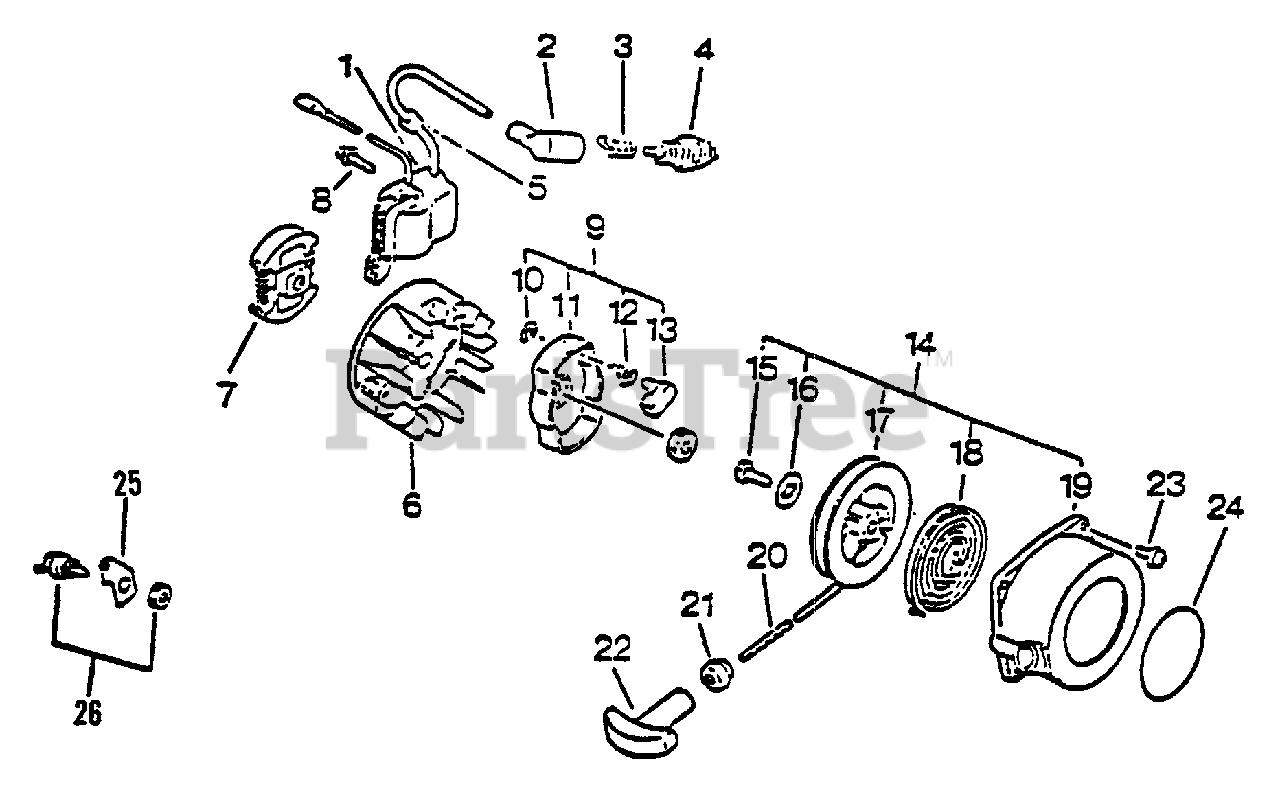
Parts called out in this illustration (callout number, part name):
1	COIL, IGNITION
2	CAP, SPARK PLUG
3	TERMINAL, SPARK PLUG CAP
4	SPARK PLUG -- BPM-7A
4	SPARK PLUG -- BPMR-7A
5	GROMMET
6	FLYWHEEL
7	CLUTCH ASSY
8	SCREW - 4X22
9	STARTER PAWL ASSY
10	RING, RETAINING - 4
11	CATCHER, PAWL
12	SPRING, RETURN
13	PAWL, STARTER
14	STARTER ASSY
16	WASHER
17	REEL, ROPE
18	SPRING, REWIND
19	CASE, STARTER
20	ROPE, STARTER - 3X890
21	GUIDE, ROPE
22	GRIP, STARTER
23	SCREW - 4X16
24	LABEL - ECHO
25	IGNITION SWITCH ASSY
26	BRACKET, SWITCH
